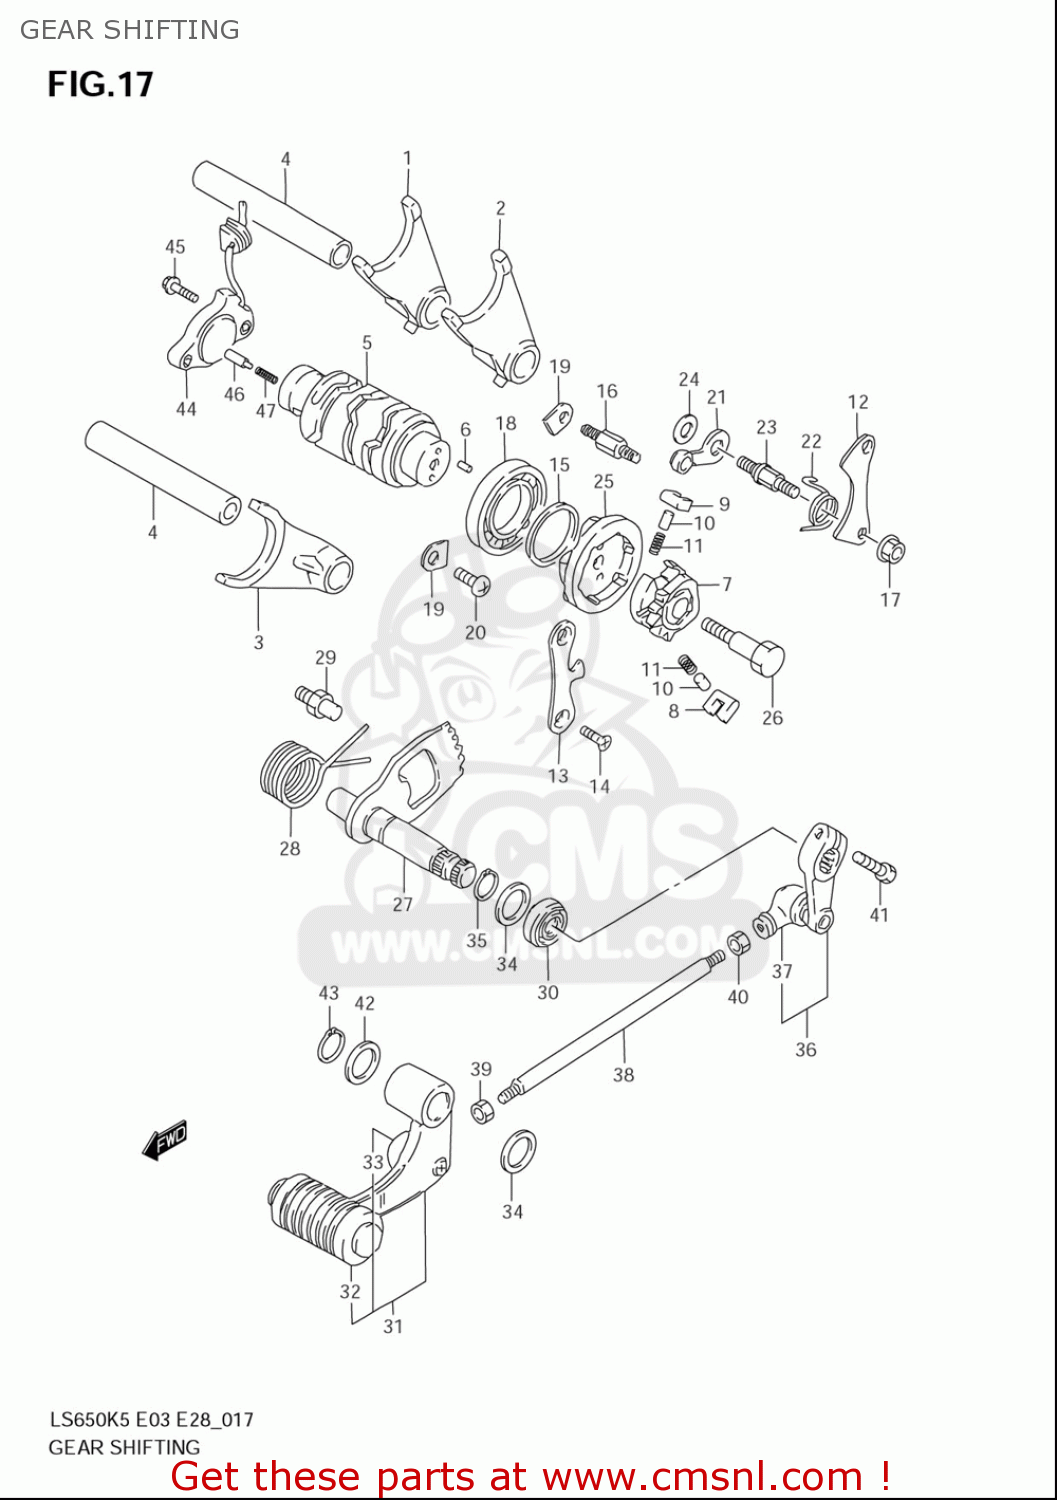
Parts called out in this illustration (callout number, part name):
1	FORK,GEAR SHIFT NO.1
2	FORK,GEAR SHIFT NO.2
3	FORK,GEAR SHIFT NO.3
4	SHAFT,GEAR SHIFT FORK
5	CAM,GEAR SHIFT
6	PIN
7	GEAR,GEAR SHIFT CAM DRIVEN
8	PAWL,GEAR SHIFT NO.1
9	PAWL,GEAR SHIFT NO.2
10	PIN(5X8)
11	SPRING
12	LIFTER,GEAR SHIFT POLE
13	GUIDE,GEAR SHIFT CAM
14	SCREW
15	WASHER(25X32X3)
16	BOSS,SHIFT PAWL LIFTER
17	NUT
18	BEARING(25X47X8)
19	RETAINER
20	SCREW
21	STOPPER,GEAR SHIFT CAM
22	SPRING
23	SUPPORT,CAM STOPPER ARM
24	WASHER
25	PLATE,GEAR SHIFT CAM
26	PIN,SHIFT CAM DRIVEN GEAR
27	SHAFT,GEAR SHIFT
28	SPRING
29	STOPPER,GEAR SHIFT ARM
30	SEAL,OIL (12X22X9)
31	LEVER ASSY,GEAR SHIFT
32	RUBBER,GEAR SHIFT PEDAL
33	COVER,DUST
34	WASHER(12.5X20X1)
35	CIRCLIP
36	ARM,GEAR SHIFT LINK
37	COVER,DUST
38	ROD,GEAR SHIFT LINK
39	NUT
40	NUT
41	BOLT
42	WASHER
43	CIRCLIP,12 MM
44	BASE ASSY,NEUTRAL SW TERMINAL
45	SCREW
46	PIN(5X15.5)
47	SPRING
